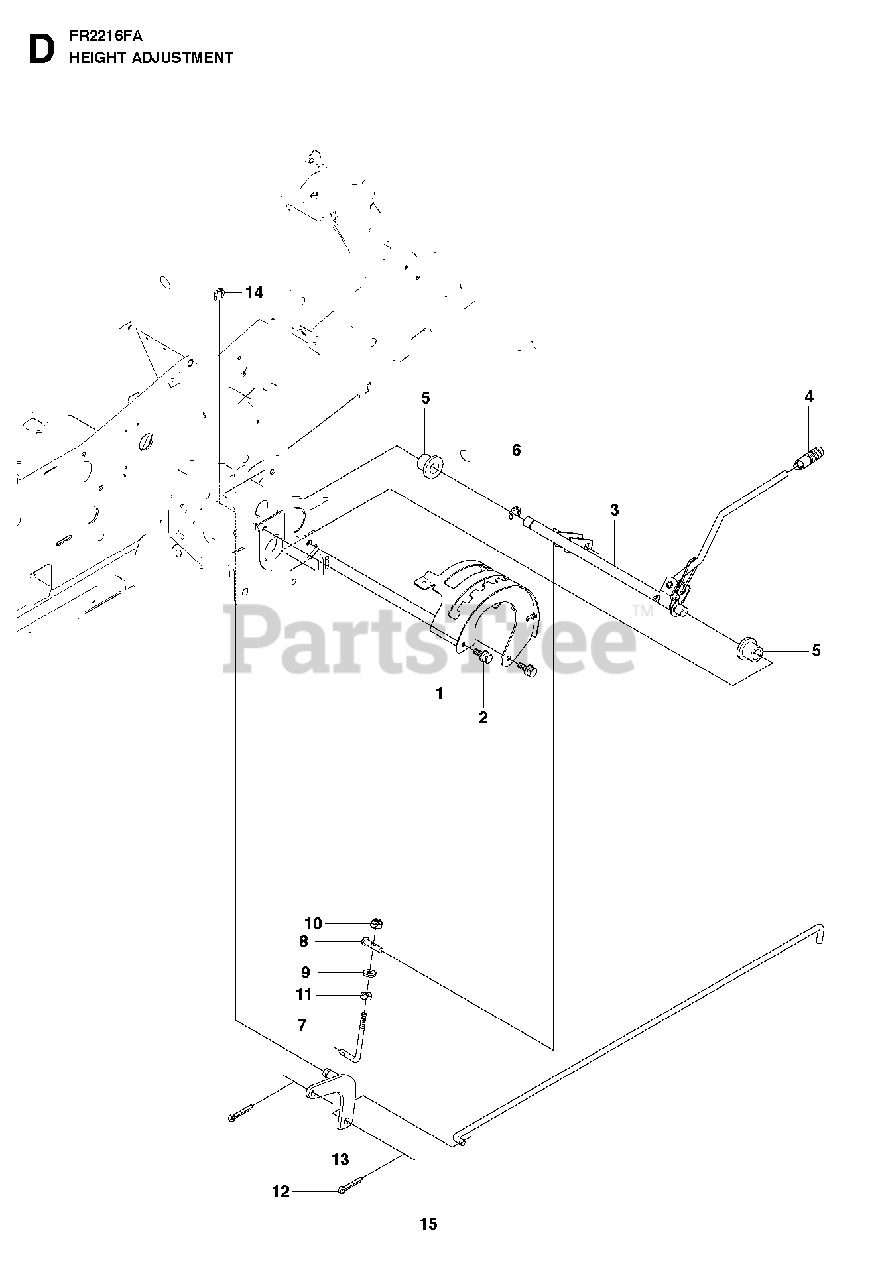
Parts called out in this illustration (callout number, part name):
1	CONTROL PLATE
4	GEAR STICK KNOB
5	BUSHING
9	WASHER
10	LOCKNUT M8
11	NUT
12	SPLIT PIN
14	RETAINING RING
15	CONNECTION ROD
